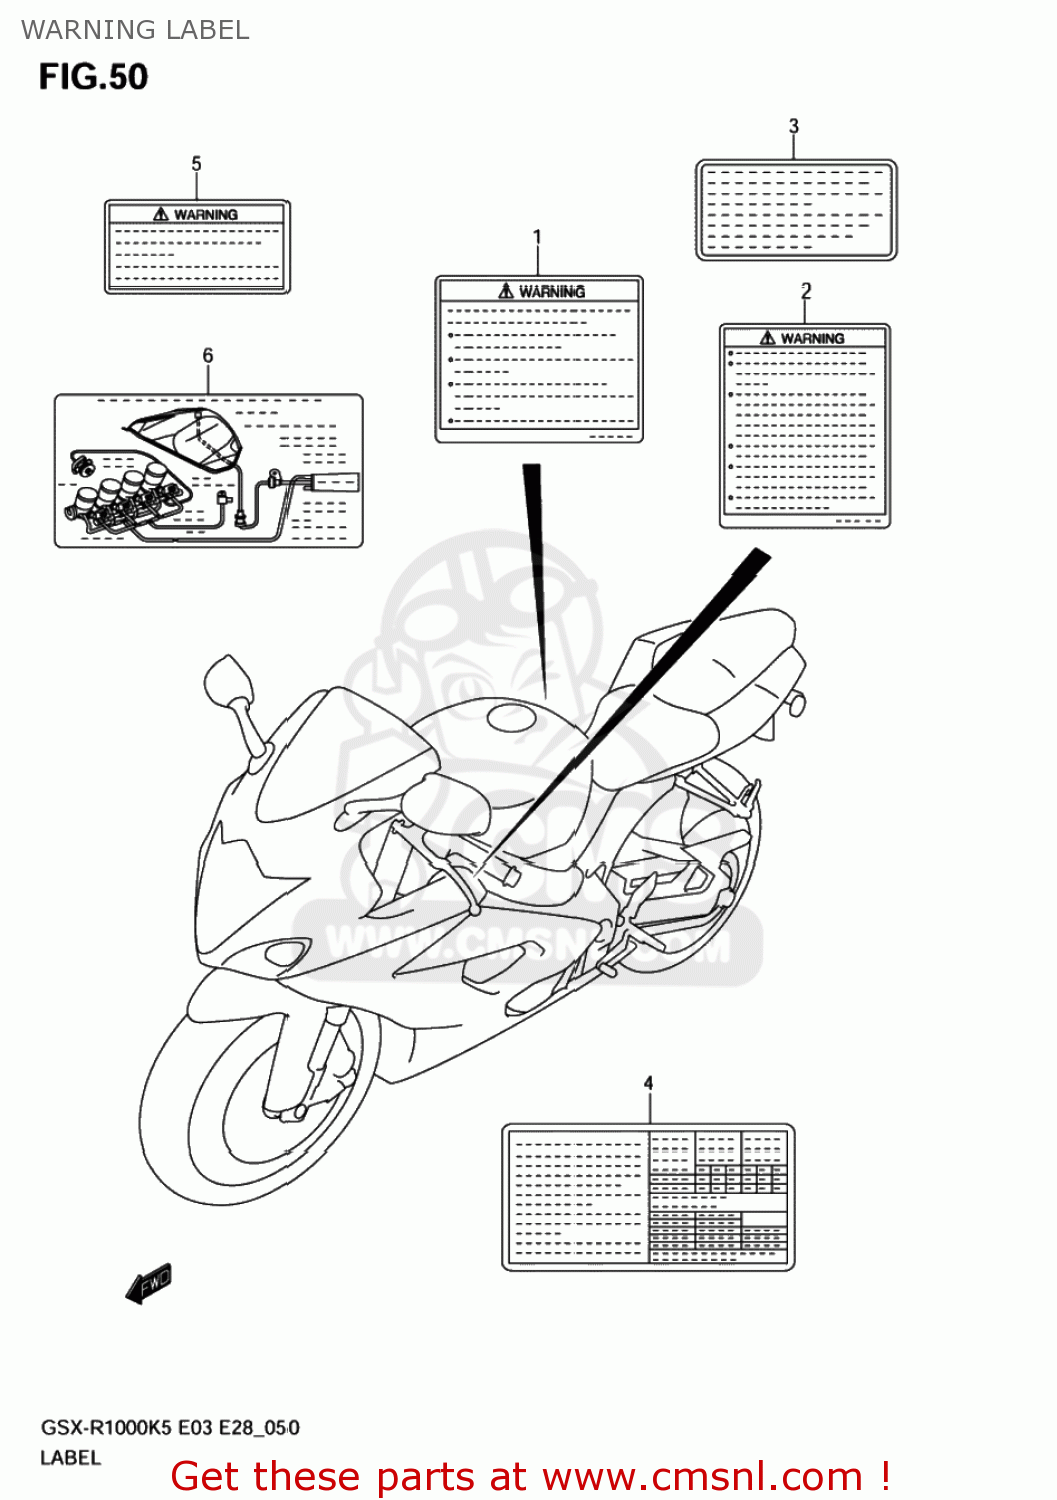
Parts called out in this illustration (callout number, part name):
1	LABEL,GENERAL WARNING
2	LABEL,SCREEN
3	LABEL,MANUAL NOTICE
4	LABEL,TIRE INFORMATION
5	LABEL,WARNING STEERING
6	LABEL,VACUUM HOSE ROUTING
7	MANUAL,OWNER'S
